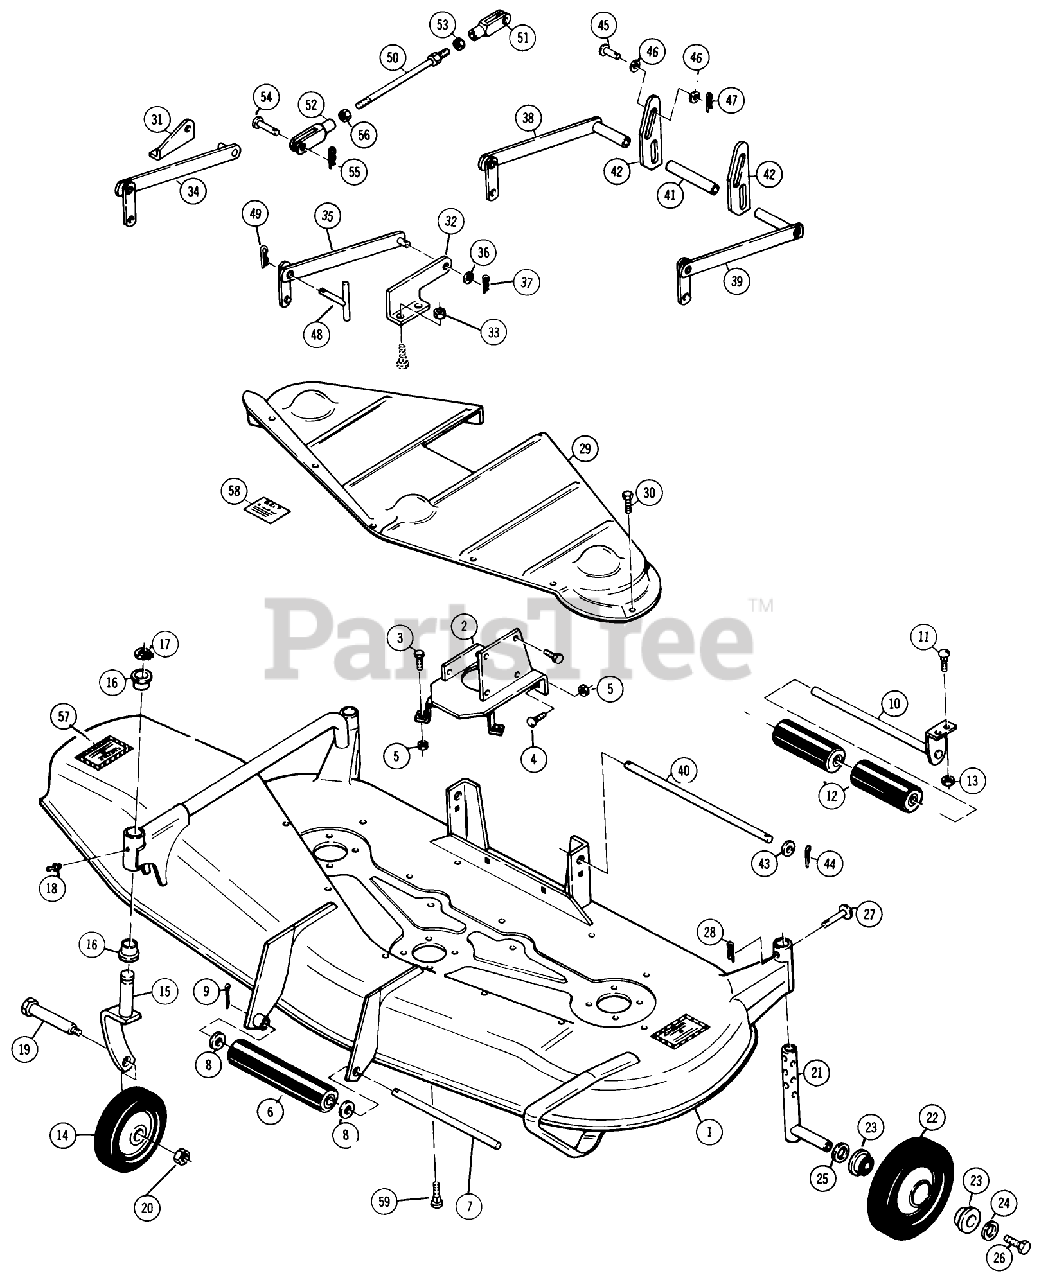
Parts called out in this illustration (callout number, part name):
1	60" Mower Deck Assembly
2	Gear Box Base
3	Bolt
4	Bolt-Carriage
5	Nut
6	ROLLER-FRONT
7	SHAFT-FRONT ROLLER
8	WASHER
9	Cotter Pin5/32 X 2
10	Rear Roller Bracket
11	Bolt
12	Rear Roller, 7"
13	Nut
14	Wheel
15	Caster Arm
16	BEARING
17	RING-SNAP, EXTERNAL
18	Zerk
19	BOLT-SHOULDER
20	Nut
21	Gauge Wheel Arm
22	Gauge Wheel (with Bearings)
23	Ball Bearing
24	WASHER 5/16 SAE
25	WASHER
26	Bolt
28	Hairpin Cotter
29	Drive Shield
30	Bolt
31	Front R.H. Bracket
32	Front L.H. Bracket
33	Nut
34	Front R.H. Lift
35	Front L.H.Lift
36	Washer
37	Hairpin
38	Rear R.H. Lift
39	Rear L.H. Lift
40	Rear Lift Rod
42	Lift Plate
43	Washer 7/8 SAE
44	PIN-4
45	Clevis Pin 5/8 x 1 1/4
46	WASHER
47	Hairpin
48	Attaching Pin
49	Hairpin
50	Rod Assembly
51	Clevis
52	Clevis (L.H. Thread)
53	Jam Nut
54	CLEVIS PIN
55	Hairpin Cotter
57	Caution Decal
58	"Belt" Decal
59	Bolt
101	Toggle
121	Set Screw
